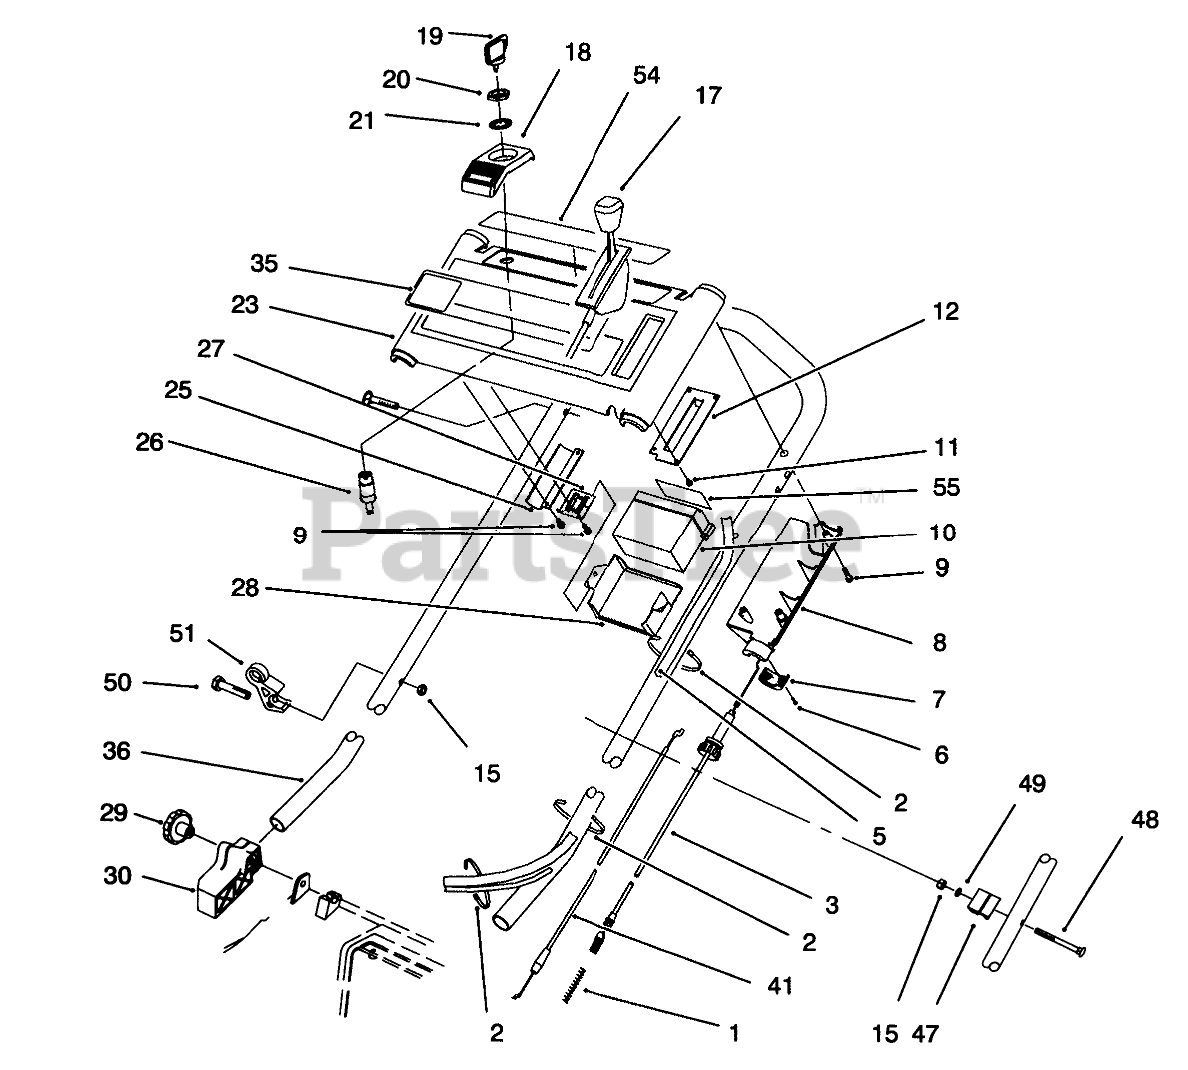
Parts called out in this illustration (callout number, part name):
1	SPRING-COMPRESSION
2	TIE-CABLE
3	ASM - TRACTION CABLE
5	WIRE HARNESS
6	#4-14X.62 PLASTITE SCW
7	LOWER THROTTLE CAP
8	COVER-THROTTLE, LEVER
9	SCREW-PPH, PLASTITE
10	BATTERY ASSEMBLY
11	#6-19X.25 PLASK FORM SC
12	THROTTLE PLATE
15	NUT-LOCK, NI
17	CONTROL - THROTTLE
18	IGNITION SWITCH BRACKET
19	KEY-IGNITION
20	NUT-HH
21	WASHER-TOOTH, INTERNAL
23	PANEL W/DECAL
25	Bracket-Panel
26	STARTER SWITCH ASM
27	BATTERY BRACKET
28	Retainer-Battery
30	MOUNT-HANDLE, RH
35	DECAL - PANEL KEY
36	Handle
41	CABLE - BRAKE
47	SUPPORT-CABLE
48	SCREW-HANDLE
49	WASHER-FLAT
50	.250-20X1.625 HH SCREW
51	GUIDE - ROPE
54	DECAL - CONTROL PANEL
55	DECAL-BATTERY
